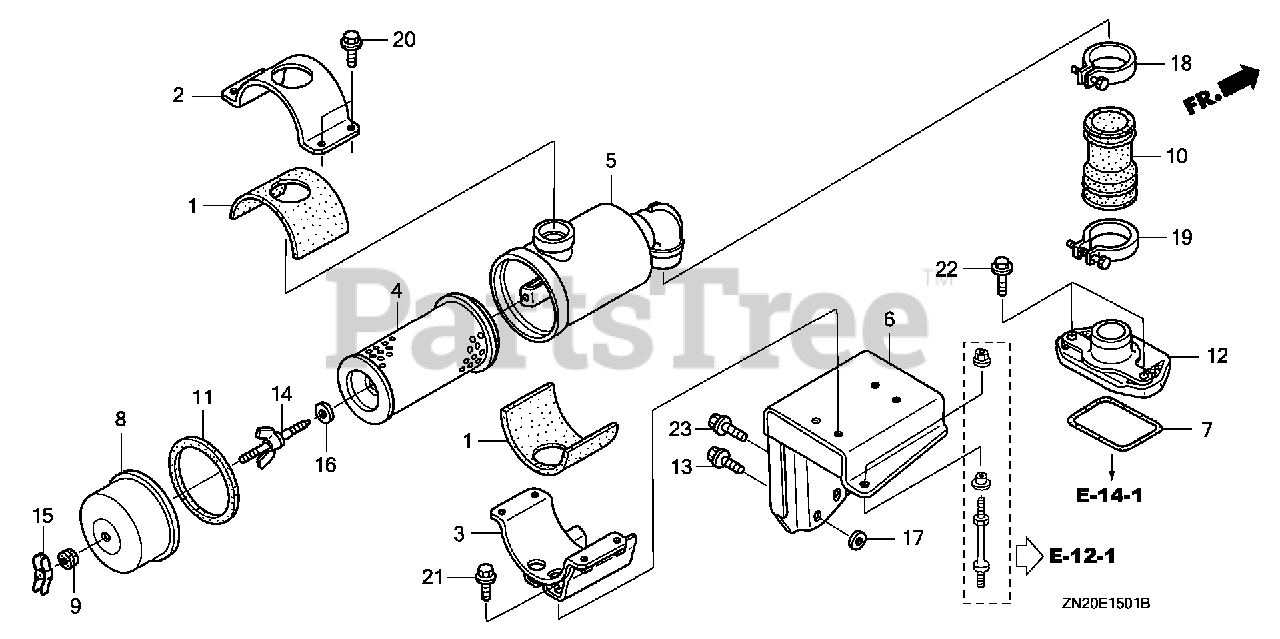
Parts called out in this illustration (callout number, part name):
1	RUBBER, AIR CLEANER HOLDER (UPPER)
2	HOLDER, AIR CLEANER (UPPER)
3	HOLDER, AIR CLEANER (LOWER)
4	ELEMENT, AIR CLEANER
5	HOUSING, AIR CLEANER
6	STAY, AIR CLEANER
7	SEAL, AIR CLEANER HOUSING
8	COVER, AIR CLEANER
9	GROMMET, AIR CLEANER
10	TUBE, AIR CLEANER CONNECTING
11	SEAL, AIR CLEANER
12	JOINT B, CONNECTING TUBE
13	BOLT, FLANGE (6X14) (CT200)
13	BOLT, FLANGE (6X18) (CT200)
14	BOLT, AIR CLEANER
15	WINGNUT (6MM) (BLACK)
16	WASHER, AIR CLEANER
17	COLLAR, SEAT
18	BAND, AIR CLEANER CONNECTING TUBE (50)
18	BAND, AIR CLEANER CONNECTING TUBE (52)
19	BAND, AIR CLEANER CONNECTING TUBE (58)
20	BOLT, FLANGE (6X12)
21	BOLT, FLANGE (6X16)
22	BOLT, FLANGE (6X28)
23	BOLT, FLANGE (8X16)
